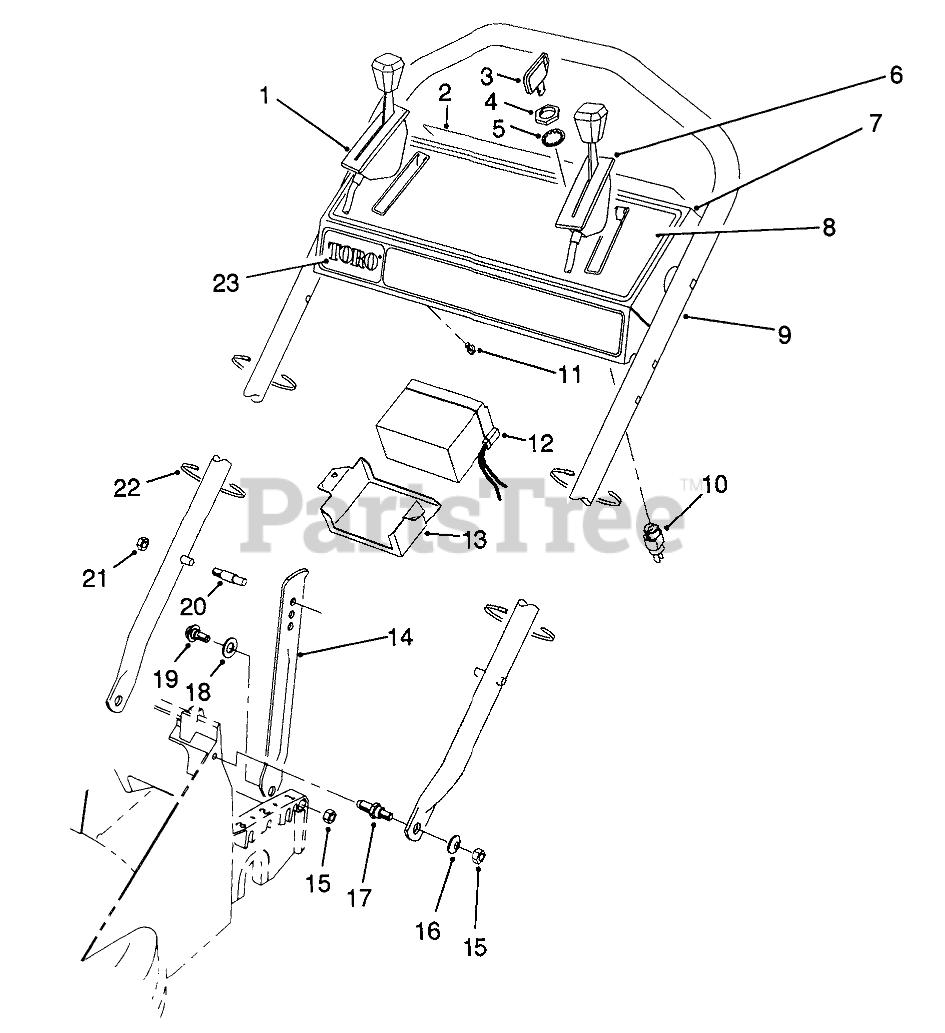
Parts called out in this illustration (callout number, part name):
1	Control-Ground Speed
2	DECAL - PANEL, REAR
3	KEY-IGNITION
4	NUT-HH
5	WASHER-TOOTH, INTERNAL
6	ControI-Throttle Bend Type #2 Sheath Lg. 44-3/4" Wire Lg. 2-1/2"
7	Panel-Control (Incl. Ref. #8)
8	DECAL - INSTRUCTION
9	HANDLE
10	Switch-Starter (Incl. Ref. #4 & 5)
11	SCREW-HWHTF
12	BATTERY ASSEMBLY
13	Retainer-Battery
14	HANDLE LATCH
15	NUT-LOCK, NI
16	WASHER-PLAIN
17	SCREW - SHOULDER STUD
18	NYLON WASHER
19	SCREW-SHOULDER
20	HANDLE PIN
21	NUT-LOCK, NI
22	TIE-CABLE
23	DECAL - KEY LECTRIC
